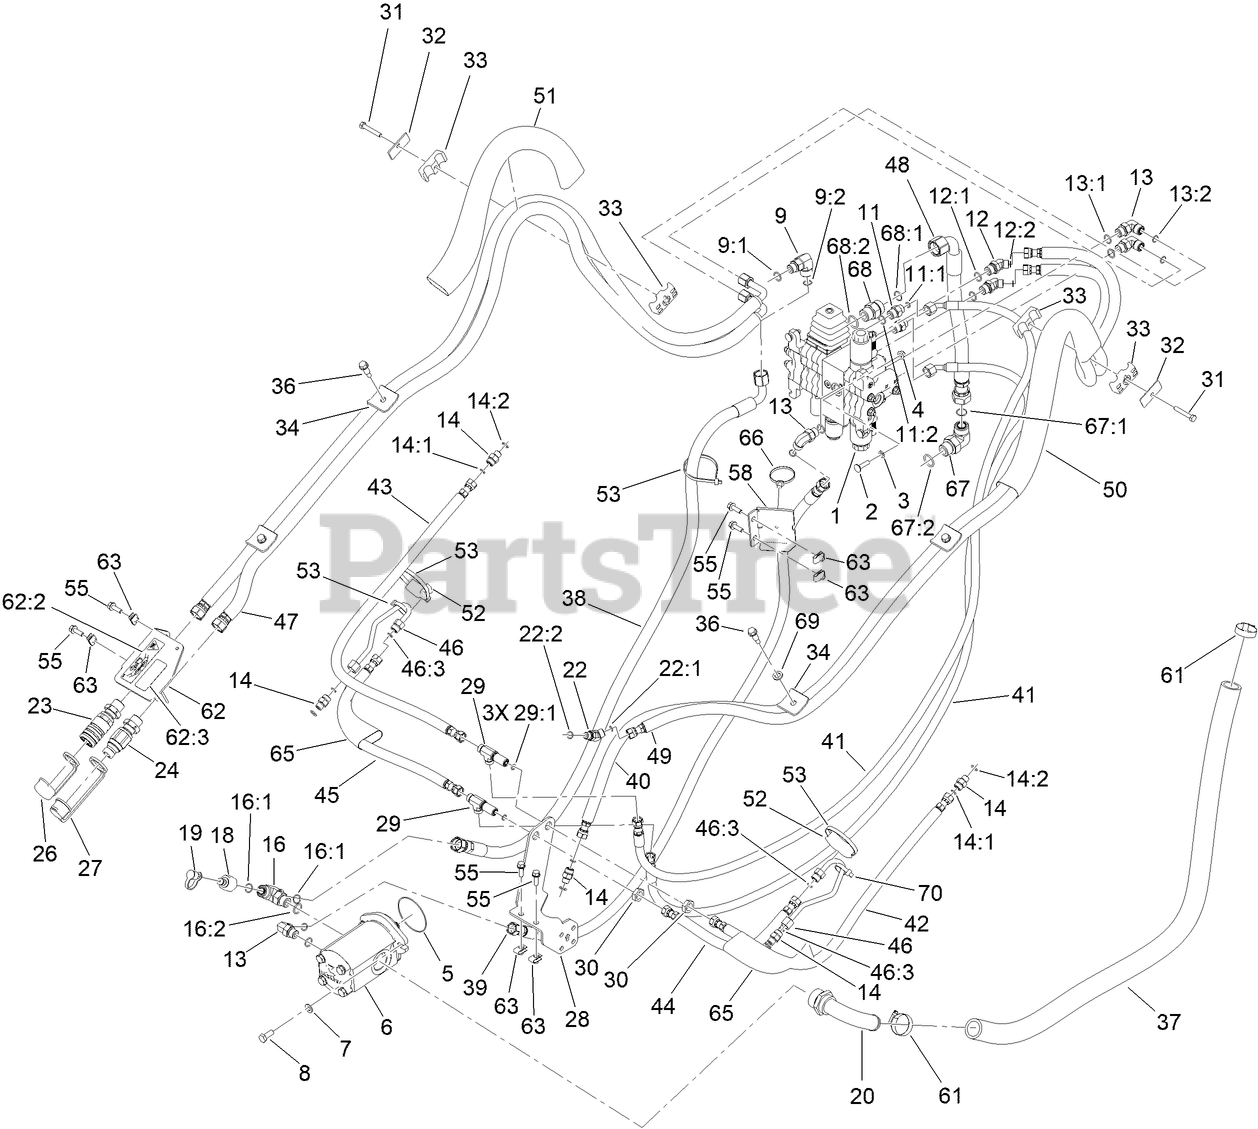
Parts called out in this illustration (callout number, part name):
1	VALVE-LOADER
2	SCREW-CARR
3	RING-RETAINING, BOLT
4	NUT-HF, NI
5	O-RING
6	PUMP-GEAR
7	WASHER-FLAT
8	SCREW-HH
9	FITTING-ELBOW, 90 DEG
9:1	O-RING
9:2	O-RING
11	FITTING-STRAIGHT
11:1	O-RING
11:2	O-RING
12	FITTING-HYD, 45 DEG
12:1	O-RING
12:2	O-RING
13	FITTING-ELBOW, 90 DEG
13:1	O-RING
13:2	O-RING
14	FITTING-STRAIGHT
14:1	O-RING
14:2	O-RING
16	TEE-ADAPTER
16:1	O-RING
16:2	O-RING
18	NIPPLE
19	CAP-DUST
20	ELBOW-90DEG
22	FITTING-ELBOW, 45 DEG
22:1	O-RING
22:2	O-RING
23	COUPLER ASM,BULKHEAD,
24	COUPLER ASM,BULKHEAD,
26	CAP-DUST, COUPLER
27	CAP-DUST, NIPPLE
28	BRACKET-BULKHEAD
29	FITTING-TEE, BULKHEAD
29:1	O-RING
30	NUT-LOCK
31	SCREW-HH
32	PLATE-COVER
33	CLAMP-TUBE
34	PLATE-HOLD DOWN
36	BOLT-SHOULDER,HHF
37	HYD HOSE
38	HYD HOSE ASM
39	HYD HOSE ASM
40	HYD HOSE ASM
41	HYD HOSE ASM
42	HYD HOSE ASM
43	HYD HOSE ASM
44	HYD HOSE ASM
45	HYD HOSE ASM
46	TUBE-HYD
46:3	O-RING
47	HYD HOSE ASM
48	HYD HOSE ASM
49	HYD HOSE ASM
50	SLEEVE-PROTECTIVE
51	SLEEVE-PROTECTIVE
52	BLOCK-HARDLINE
53	TIE-CABLE
55	SCREW-HHF
58	BRACKET-GUIDE, HOSE
61	CLAMP-HOSE
62	BRACKET ASM-QC
62:2	DECAL-CAUTION
62:3	DECAL-WARNING, HYD PRESSURE
63	NUT-CLIP, U
65	SLEEVE-PROTECTIVE
66	CLIP-TIE
67	FITTING-ELBOW-90
67:1	O-RING
67:2	O-RING
68	FITTING-HYD, STRAIGHT
68:1	O-RING
68:2	O-RING
69	SPACER-BEARING
70	TIE-CABLE
